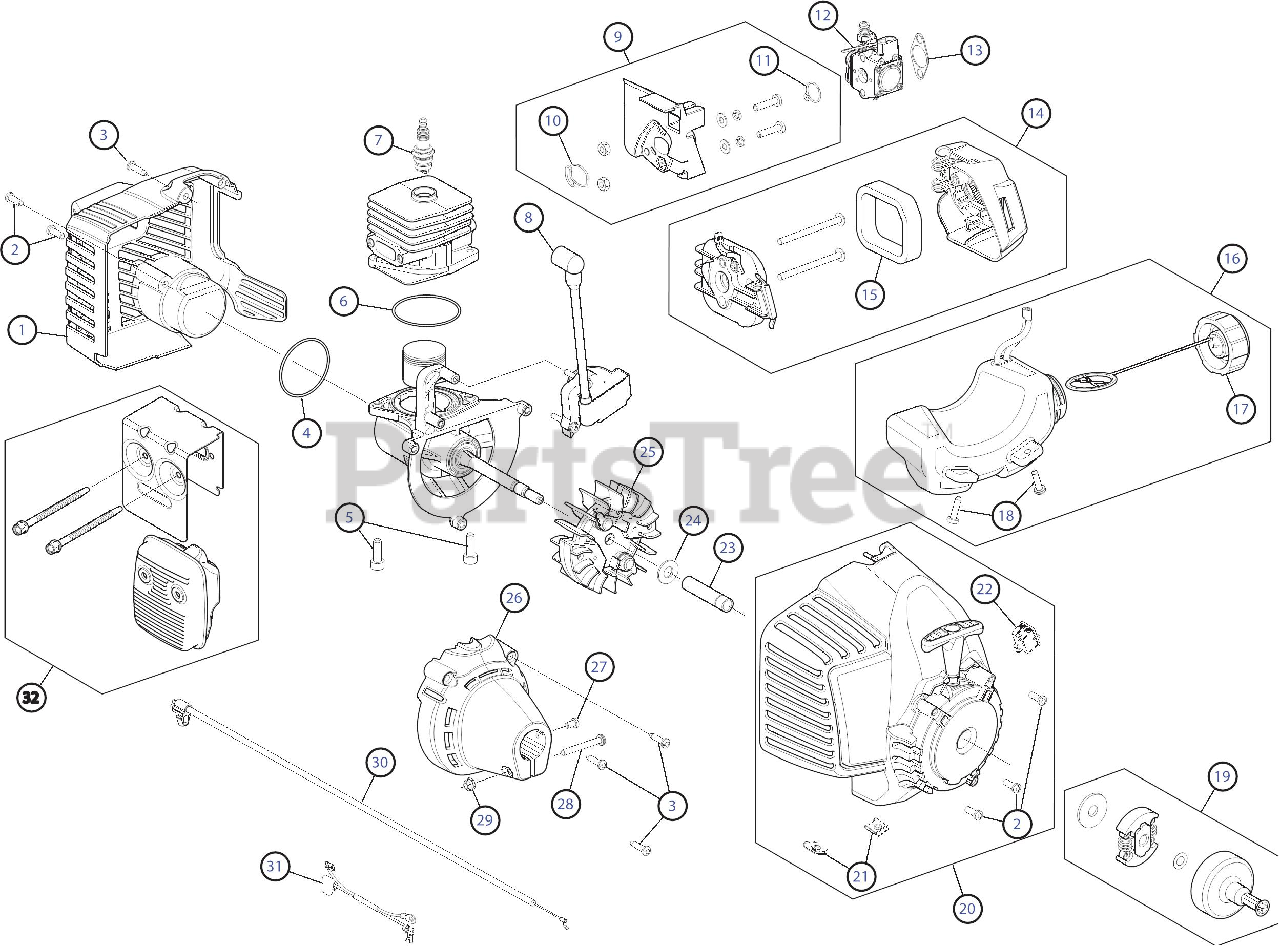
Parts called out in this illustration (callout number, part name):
1	Rear Cover Assembly (includes 2 & 3)
2	Housing Screw
3	Cover Screw
4	O-Ring
5	Crankcase Bolt
6	Crankcase O-Ring
7	Spark Plug
8	Module Assembly
9	Insulator Assembly (includes 10 & 11)
10	Insulator O-Ring
11	Carburetor O-Ring
12	Carburetor
13	Air Cleaner Gasket
14	Air Cleaner Cover Assembly (includes 15)
15	Air Cleaner Filter
16	Fuel Tank Assembly (includes 17 & 18)
17	Fuel Tank Cap
18	Fuel Tank Screw
19	Starter Clutch Assembly
20	Starter Housing (includes 2, 21 & 22)
21	U-shaped Nut
22	Switch Assembly
23	Spacer
24	Washer
25	Flywheel Assembly
26	Clutch Cover (includes 3)
27	Anti-rotation Screw
28	Clamp Screw
29	Clamp Nut
30	Throttle Cable
31	Lead Wires
32	Muffler Assembly
